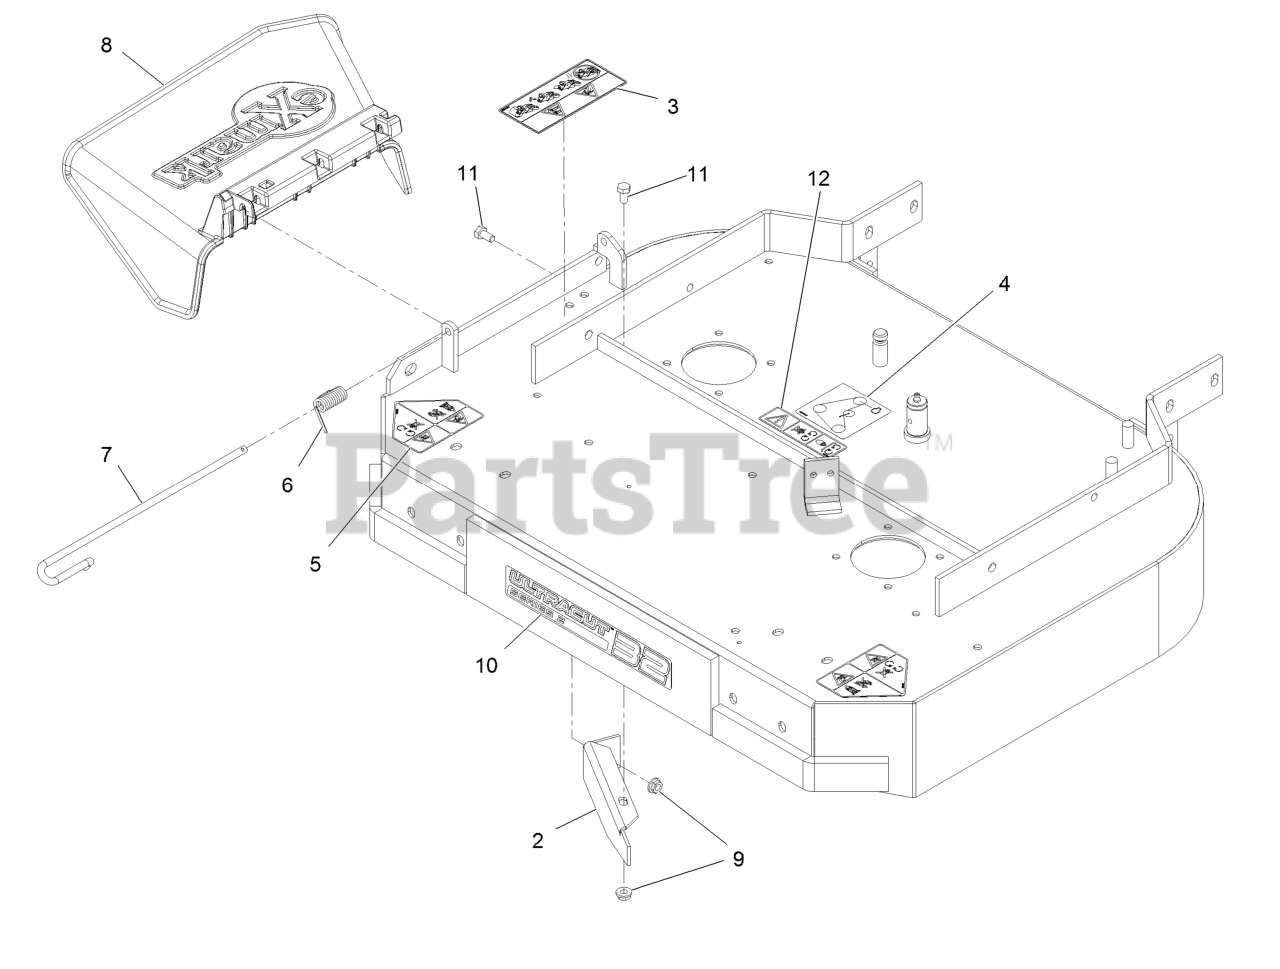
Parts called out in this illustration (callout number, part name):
2	Baffle-Dogleg
3	Decal-Warning, Bagger
4	Decal-Belt Routing 32-36
5	Decal-Danger
6	Spring, Torsion
7	Pin-Chute
8	Deflector-Discharge
9	Nut-Whizlock 5/16-18
10	Decal-Ultracut 32 Series 2
11	Screw-HH 5/16-18 X 5/8
12	Decal-Cover, Missing
